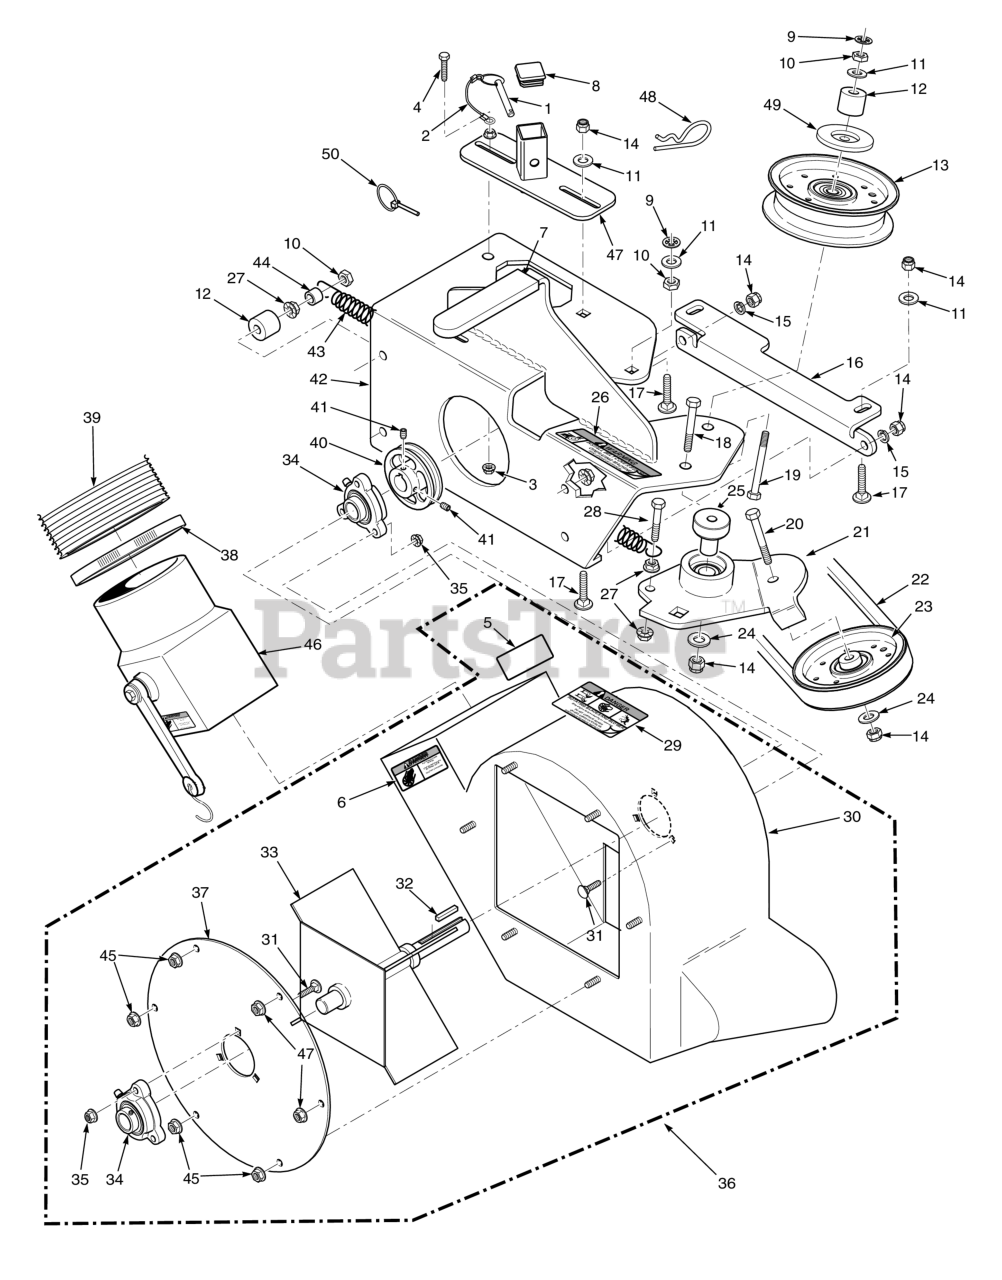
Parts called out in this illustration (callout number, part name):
1	Pin, Ring 1/2 x 2-1/4"
2	Lanyard, Deck Height Pin
3	NUT, 1/4-20 SERRATED FLANGE HEX HEAD
4	SERR. FLG. HEX HEAD CAPSCREW, 5/16-18 X 3/4
5	Decal, Blower
6	Decal, Rotating Blower
7	Grip, Deck Latch Lever
8	Cap, Square Vinyl
9	Nut, Push-On - 3/8" Dia.
10	Bolt, Hex Head 3/8-16 x 1" Ser. Flg.
11	Flatwasher, 3/8" Special (.391 x .938 x .105)
12	SPACER, J-PULL ROD
13	Pulley, Idler 4" Dia. - 61" & 72"
14	HEX NUT, ELASTIC STOP LOCK, 3/8-16
15	Lockwasher, 3/8" Spring, Kawasaki FX / FT & FT-EFI / B&S 32BV
16	Plate, Catcher Mounting
17	Bolt, RDHD Carr. 3/8-16 x 1-1/2 (52" & 61")
18	Bolt, Hex Head 3/8-16 x 3" - 52"
19	Bolt, Hex Head 3/8-16 x 3-1/2" Full Thread
20	Bolt, Hex Head 3/8-16 x 1-3/4" (Kohler EFI)
21	Idler Arm Assembly, GC-STT 61"
22	Belt, GC-STC-61V / STCII-61V
23	Pulley, 3-1/2" O.D., GC-STT 52"
24	Flatwasher, 3/8 (.391 x .938 x .105 HD) Grade 8
25	Pivot, Idler - 61" & 72"
26	Decal, Warning - Belt Cover
27	NUT, 3/8-16 SERRATED FLANGE HEX HEAD
28	Bolt, Hex Head 3/8-16 x 1-1/2" Grade 8 Black
29	Decal, Danger
30	Blower Housing Weldment w/Decals
31	Bolt, 5/16-18 x .75 RHSN Carriage
32	KEY 1/4 X 1/4 X 1 1/2"(FOR 1" CRANKSHAFT
33	Fan Weldment
34	Bearing Assembly
35	HEX NUT, ELASTIC STOP LOCK, 5/16-18
36	Blower Housing Assembly, GC-STT
37	COVER, BLOWER HOUSING
38	Clamp, 8-5/8" Max Dia. (61")
39	Hose, 8.00" Dia. x 68" Long
40	Pulley, 4-3/4" O.D. - 1" Bore
41	Setscrew, Hex Socket Knurl Cup Pt. 5/16 - 18 (nylock)
42	Frame, Blower Mount
43	Spring, Helper (61" Cutter Deck Only)
44	Spacer, Deck Assist
45	Nut, Serrated Flange 5/16-18 (Right Front Engine Mounting, Briggs and Kohler Only)
46	Adapter, Blower GC-STC,
47	Receiver Weldment, Mount Post - 61"
48	Hair Pin Cotter, .177" x 3-1/4"
49	Quick Pin, 5/16" Dia.
50	Quick Pin, 5/16" Dia.
